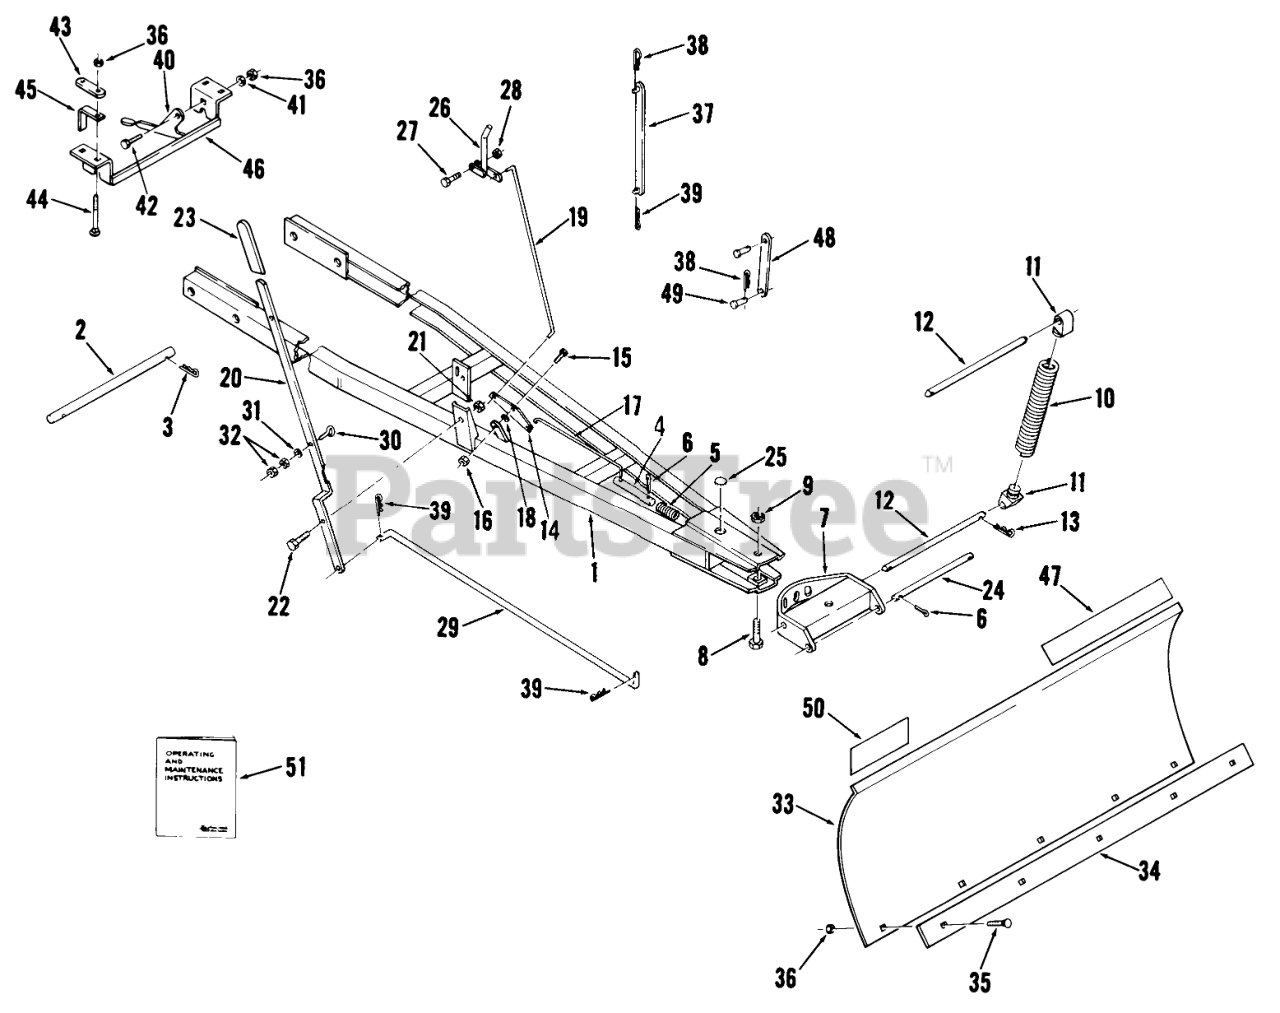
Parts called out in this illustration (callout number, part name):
1	Ass-y. Frame
2	Mounting Shaft
3	Hairpin
4	Index Pin
5	SPRING-COMPRESSION
7	Sector and Channel
8	Bolt
9	Nut
10	Spring
11	Lug
12	ROD-PIVOT, BLADE
13	Hairpin
14	Index Plate
15	BOLT
16	NUT
17	Head-Cylinder
18	Washer
19	UPPER INDEX ROD
20	Index Lever
21	Jam Nut
22	Bolt
23	GRIP
24	ROD-LOWER
25	PLUG
26	INDEX LEVER
27	Bolt
28	Nut
30	Eye Bolt
31	Lockwasher
32	Hex Nut
33	Blade
34	Plate
35	Bolt-Carriage
36	NUT
37	LIFT BAR ASSY R
38	Hairpin Cotter
39	Hairpin
40	PLATE-LATCHING
41	Washer
42	BOLT
43	BRACKET-REAR LINK MOUNTING
44	Bolt-Carriage
45	SPACER-BRACKET
46	Bracket
47	DECAL-WHEEL HORSE
48	LINK-LIFT
49	Pin
50	Caution Decal
51	Operating and Maintenance Instructions
